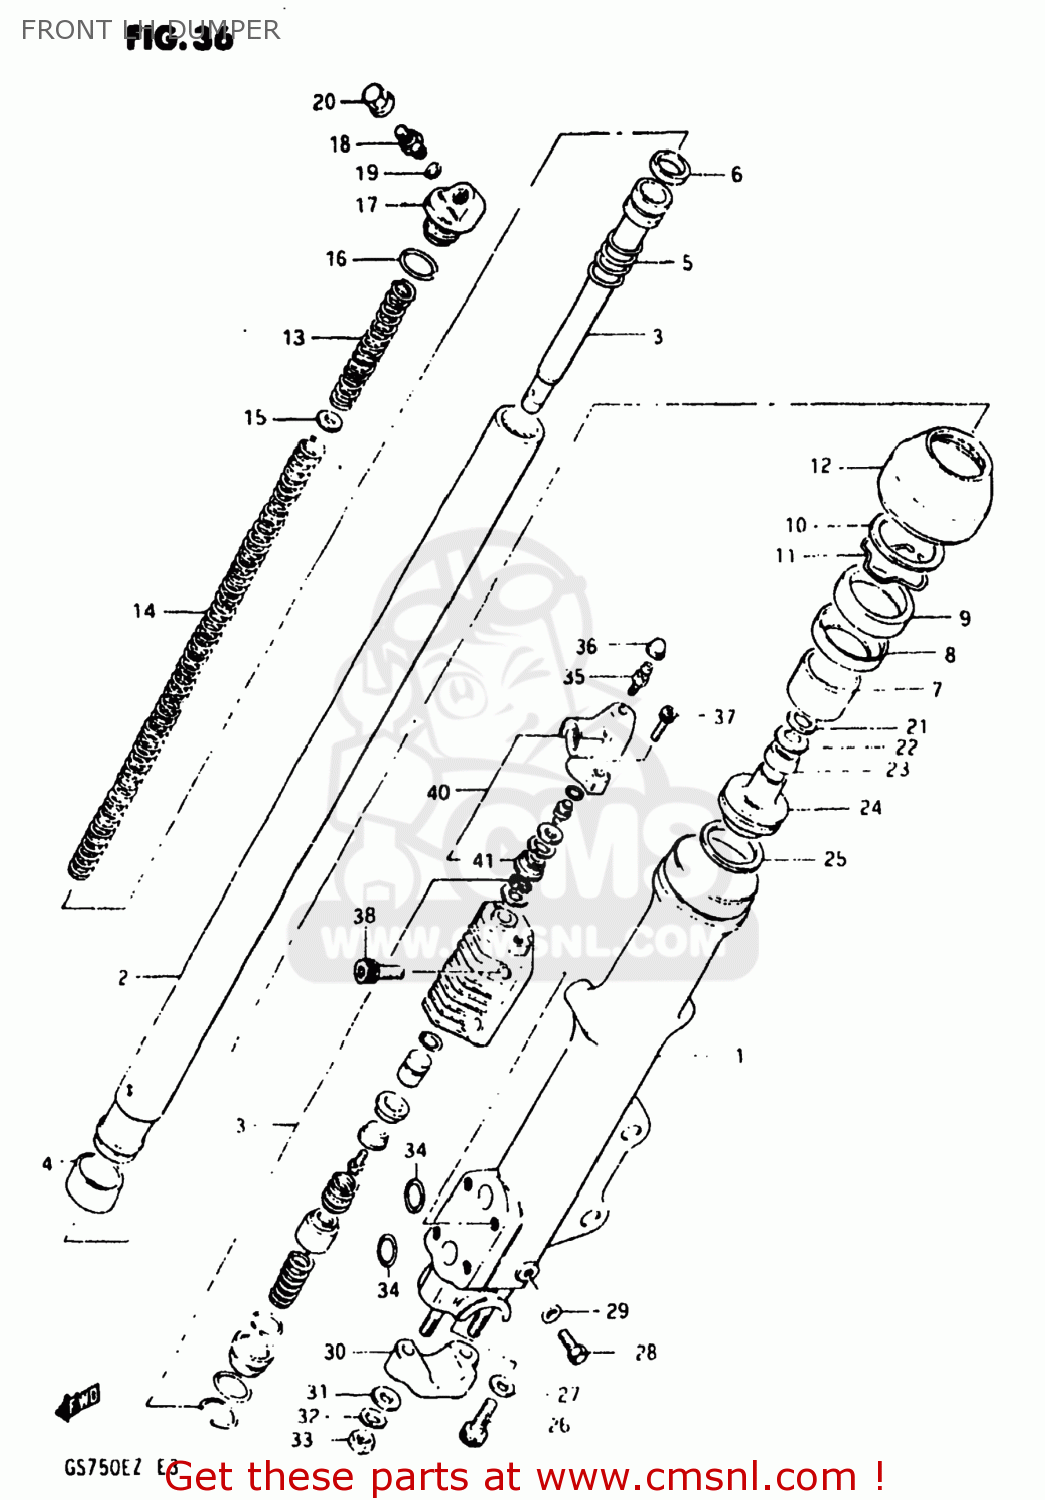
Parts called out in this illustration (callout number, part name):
1	TUBE,FORK,LEFT,OUTER
2	TUBE,FORK,INNER
3	CYLINDER,FRONT FORK
4	PISTON
5	SPRING,FORK REBOUND
6	RING
7	BUSH,GUIDE
8	SPACER,SEAL
9	OIL SEAL,FRONT FORK
10	RING,FR FORK
11	CIRCLIP,FORK OIL SEAL
12	BOOT
13	SPRING
14	SPRING,FRONT FORK
15	WASHER,SPRING
16	O-RING
17	BOLT,FORK INNER TUBE
18	VALVE,AIR
19	O-RING
20	CAP
21	VALVE
22	SPRING,VALVE
23	VALVE,OIL LOCK PIEACE
24	PIECE,FRONT FORK OIL LOCK
25	PISTON RING,FRONT FORK
26	BOLT(8X27)
27	GASKET (NAS)
28	BOLT
29	GASKET,DRAIN,PLUG (NAS)
30	HOLDER,AXLE
31	WASHER
32	LOCK WASHER
33	NUT
34	O RING,FR FORK
35	BREATHER
36	CAP
37	BOLT
38	BOLT
39	MODULATOR VALVE SET,FRONT
40	MODULATOR PARTS SET,FRONT
41	SEPARATOR,FRONT FORK MODULATOR
